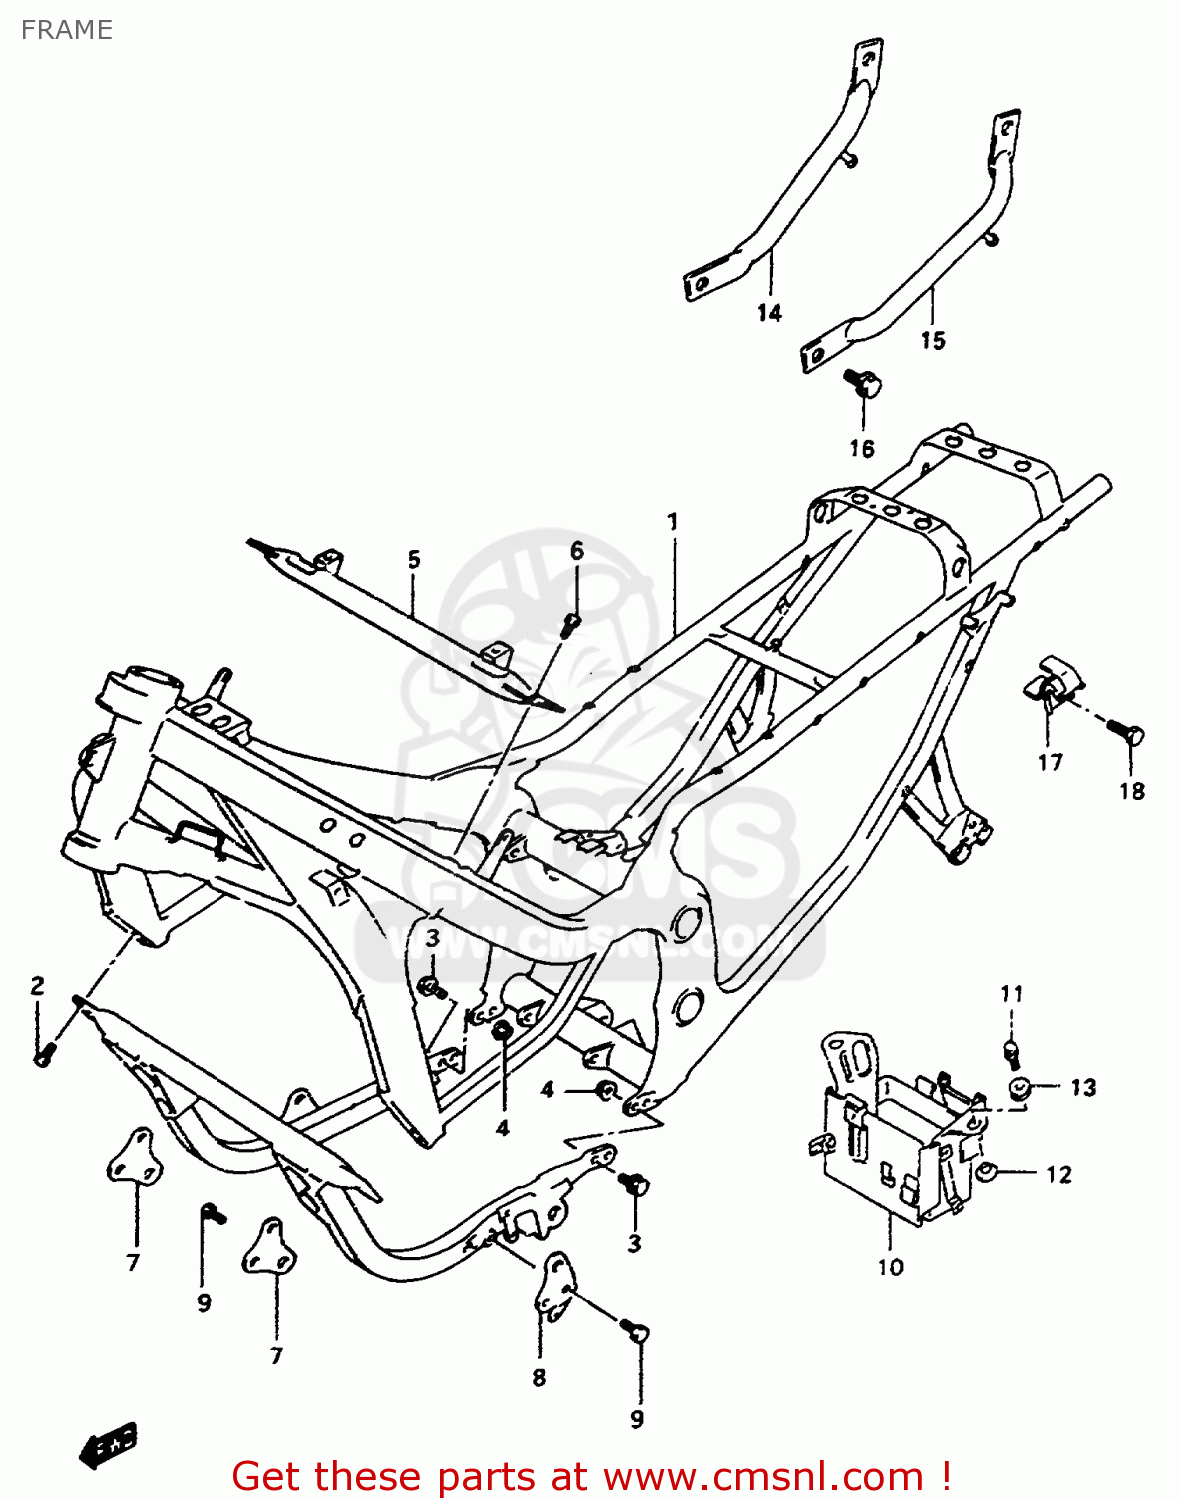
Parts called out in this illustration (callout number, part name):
1	FRAME SET (BLACK)
2	BOLT
3	BOLT
4	NUT
5	TUBE,FRAME BRIDGE NO.2
6	BOLT(8X20)
7	PLATE,ENG MTG NO.1
8	PLATE,ENG MTG NO.2,L
9	BOLT, UPPER
10	HOLDER,BATTERY
11	BOLT
12	WASHER
13	CUSHION
14	GRIP,REAR,RIGHT
15	GRIP,RR,L
16	BOLT
17	HOLDER,HELMET
18	BOLT
